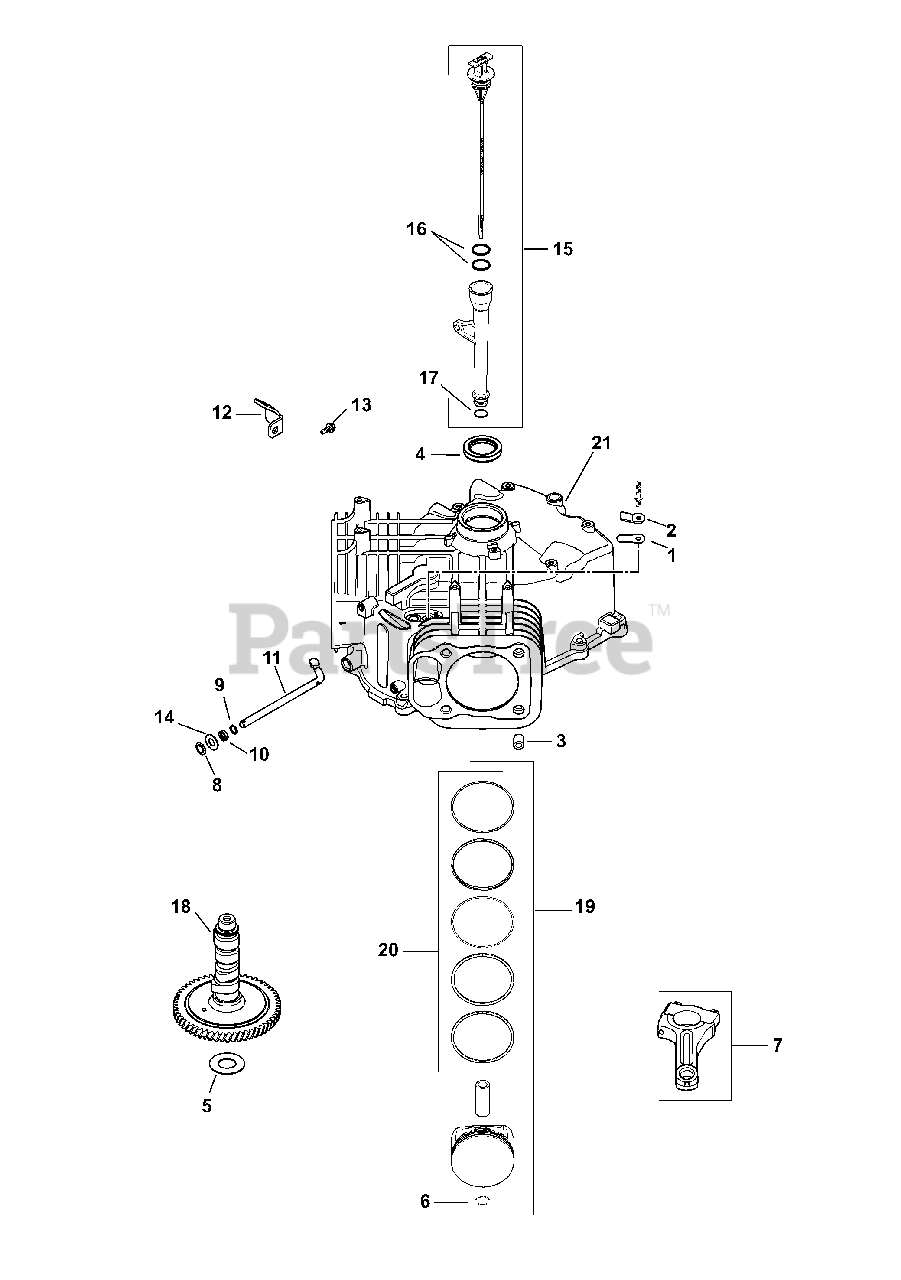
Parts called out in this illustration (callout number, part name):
1	Breather Reed
2	Breather Reed Retainer
4	Oil Seal, 1.78 x 1.26
5	Camshaft Shim (White, .028)
5	Camshaft Shim (Blue, .03)
5	Camshaft Shim (Red, .032)
5	Camshaft Shim (Yellow, .034)
5	Camshaft Shim (Green, .036)
5	Camshaft Shim (Gray, .038)
5	Camshaft Shim (Black, .04)
6	Piston Pin Retainer
7	Connecting Rod (STD)
8	Ring Retainer
9	Flat Washer, 11/32
10	Governor Cross Shaft Seal
11	Governor Cross Shaft
12	Oil Fill Tube Bracket
13	Flange Screw, M5 x .8 x 13
14	Flat Washer, 9mm
15	Dipstick & Tube Kit
17	Lower Oil Fill Tube O-Ring
18	Camshaft Assembly
19	Piston W/ Ring Kit (STD)
19	Piston W/ Ring Kit (0.25) 83mm
19	Piston W/ Ring Kit (0.08) 83mm
20	Ring Set (STD)
20	Ring Set (.08)
20	Ring Set (.25)
21	Crankcase (Use Short Block)
